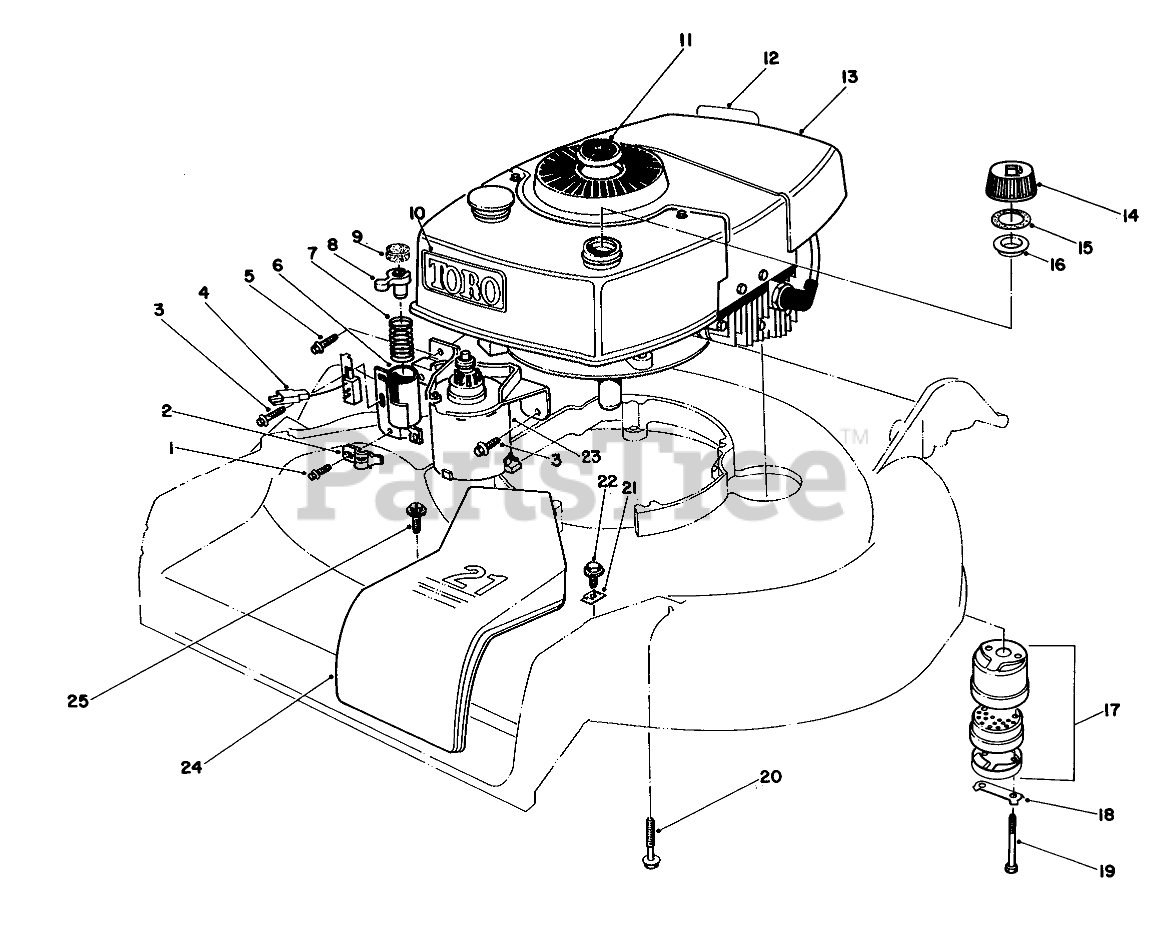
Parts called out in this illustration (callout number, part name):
1	SCREW
2	CABLE CLAMP
3	SCREW
4	PUSH BUTTON SWITCH
5	Screw
6	TUBE W A
7	COMPRESSION SPRING
8	Plunger
9	Pad-Friction
10	Decal Tow
11	PLUG BUTTON
12	Decal-Maintenan
13	Engine
14	Gas Cap Assembly (Incl. Ref. #15 & 16)
15	GASKET
16	GAS CAP BAFFLE
17	Muffler Assembly (Incl. Ref. #18 & 19)
18	CLIP - LOCKING
19	SCREW-HH
20	3/8-16 X 2-3/4 CAPSCR
21	Cable Clamp
22	SCREW-HWHTF
23	Starter Motor
24	BELT COVER 21" S D
25	SCREW
